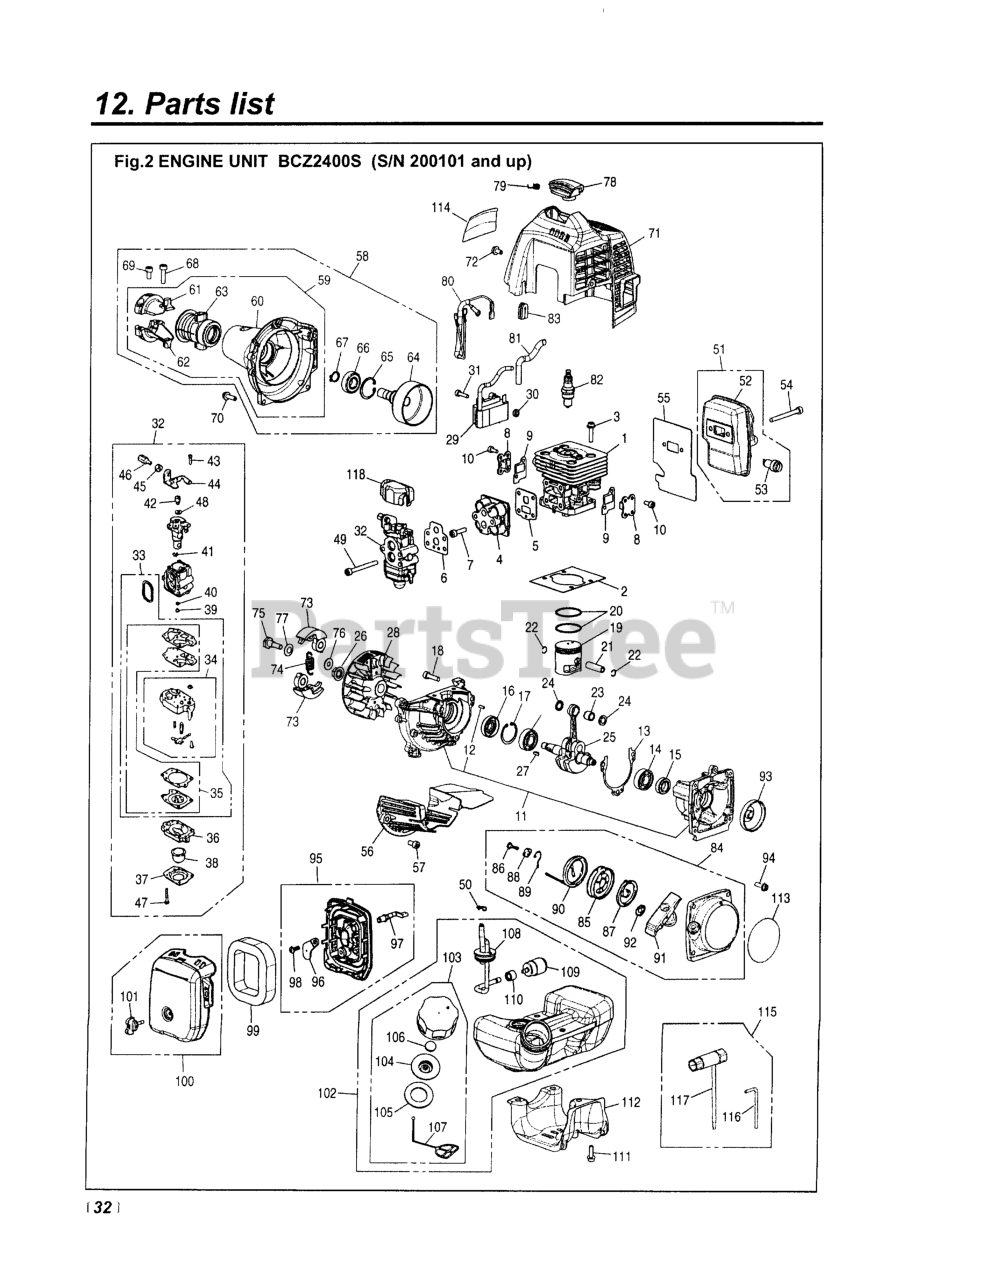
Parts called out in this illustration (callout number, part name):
1	CYLINDER
2	GASKET, BASE
3	BOLT
4	INSULATOR
5	GASKET, INSULATOR
6	GASKET, CARB.
7	BOLT, TORX
8	COVER, TR
9	GASKET, TR
10	BOLT, TORX
11	CRANKCASE-C
12	PIN
13	GASKET, CASE
14	BEARING
15	SEAL
16	SEAL, OIL (RPLS 1140-21220)
17	RING, SNAP, M28 x 1.2
18	BOLT (RPLS 2850-14220)
20	RING, PISTON
21	PIN, PISTON
22	RING, SNAP (RPLS 1101-41320)
23	BEARING
24	WASHER
25	CRANKSHAFT COMP.
27	KEY
28	ROTOR
29	COIL-A
30	SPACER (RPLS -71260)
31	BOLT TORX
33	REBUILD KIT
34	BODY-A
35	KIT, GASKET (REPLACES-06020)
36	BODY, PURGE
37	COVER, PUMP
38	PUMP, PRIMING
39	JET
40	RING, O
41	RING
42	SWIVEL
43	SCREW
45	NUT, CABLE ADJUSTER
46	SCREW, CABLE ADJUSTER
47	SCREW
48	WASHER
49	BOLT
50	CLIP
51	MUFFLER ASSEMBLY
52	MUFFLER (REPLACES -15110)
53	ARRESTER
54	BOLT
55	GASKET, MUFFLER
56	PLATE
57	BOLT
59	HOUSING COMP (RPLS. -31110)
61	BRACKET (A) (RPLS -31211)
62	BRACKET (B)
63	CUSHION (RPLS -31231)
65	RING, SNAP, M28 x 1.2
67	RING, SNAP (RPLS 3130-13270)
68	BOLT (RPLS 2850-14220)
69	BOLT
70	BOLT
71	COVER, ENGINE
73	SHOE
74	SPRING
75	BOLT
76	WASHER, FLAT (USE 182303)
77	WASHER (RPLS -51241)
78	CAP (RPLS 4810-72110)
79	SPRING
80	CORD COMP.
82	SPARK PLUG (CMR7H)
83	GROMMET
84	RECOIL-A
85	REEL
86	SCREW
87	SPRING, SPIRAL
88	COLLAR
89	ARM
90	ROPE (REPLACES 4500-75160)
91	KNOB (RPLS -75420)
92	PLATE, STOPPER
93	PULLEY
94	BOLT
96	PLATE, CHOKE
97	LEVER
98	SCREW
99	ELEMENT
101	KNOB
102	TANK-A
103	CAP ASSY (RPLS -85201)
104	HOLDER (REPLACES -85230)
105	PACKING
106	FILTER
107	STOPPER
109	FILTER ASSY
111	BOLT
112	GUARD, TANK
113	LABEL, RECOIL
114	LABEL, COVER
116	BAR
118	COVER
